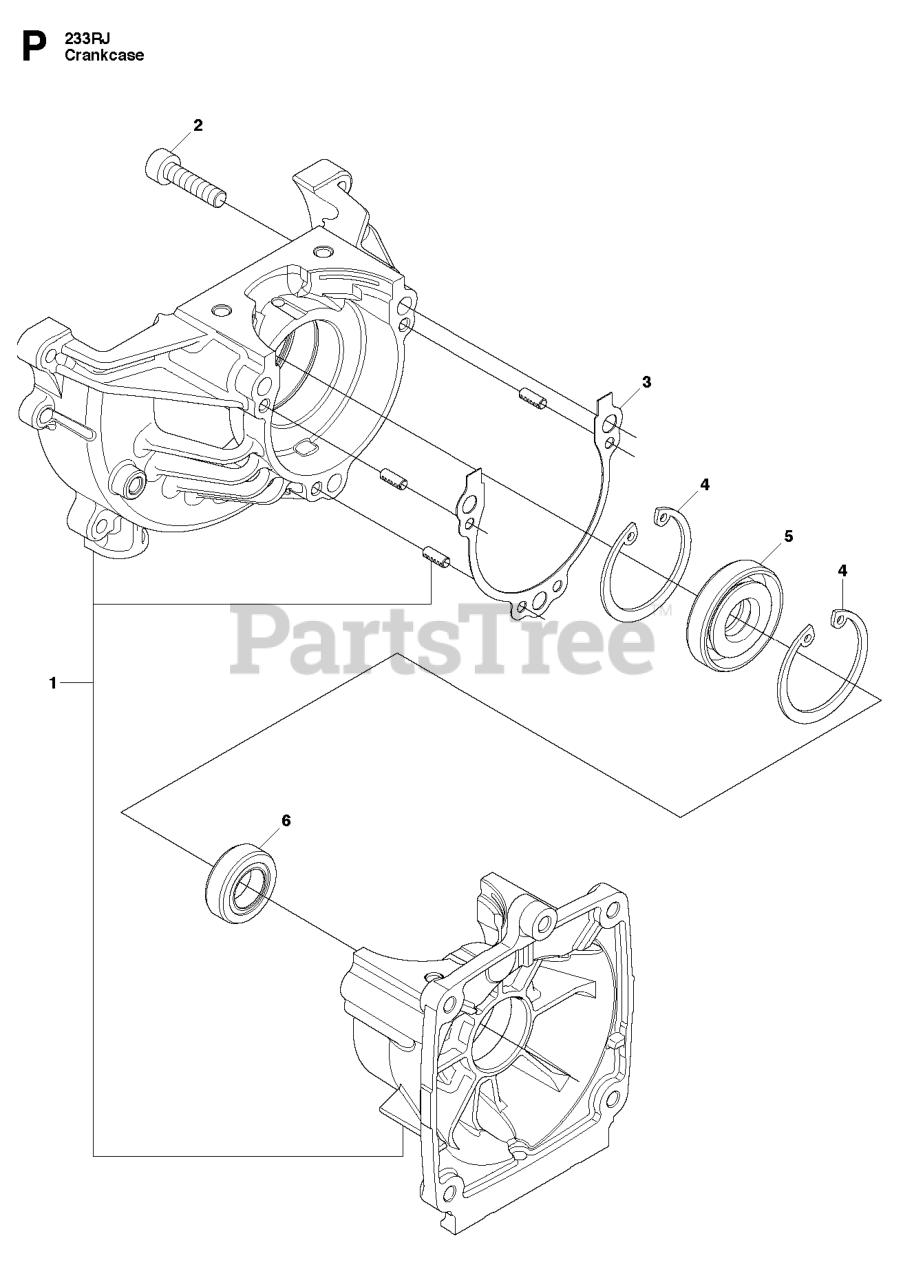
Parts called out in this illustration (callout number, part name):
1	CRANKCASE-C
2	RP BOLT TORX M5XL20 T27
3	GASKET
6	SEAL
